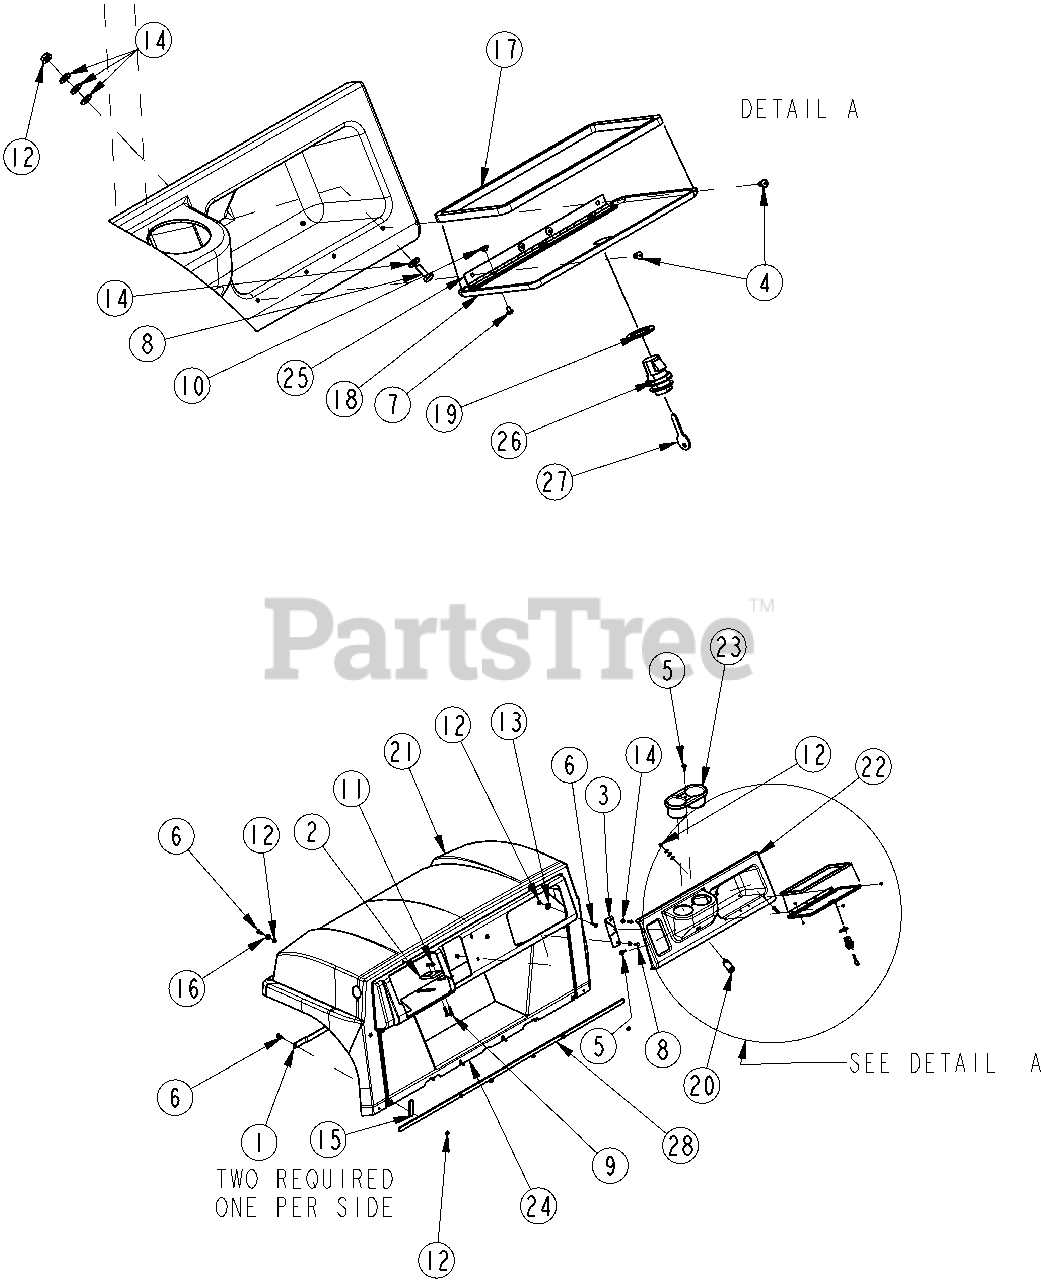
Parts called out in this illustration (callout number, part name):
1	BACKING PLATE FOR TRUCK BODY
2	BODY MOUNT SPACER .375 THICK As Required
2	BODY MOUNT SPACER .25 THICK As Required
3	DASH MOUNT PLATE
4	RIVET POP 3/16 .126-.250
5	RIVET, 1/4 REMOVEABLE
6	TPHMS Y 1/4-20X1 YELLOW DIE
7	PHMS #8-32 X 1/4, SS BLACK
8	HHCS 1/4-20X3/4 GR5
9	HHCS 5/16-18X1 1/4 GR5
10	NUT, BINDER 8-32 X 1/8
11	NUT HEX FLG TOP LK 5/16-18 YLW
12	NUT HEX FLNG T-LOCK 1/4-20 PLT
13	WASHER FLAT 3/8 USS PLT
14	WASHER FLAT 1/4 HARD ASTMF436
15	TRIM, 1/8 RUBBER EDGE (PER FT)
16	RUBBER GROMMET .75DX.31IDX.37T
17	SEAL, GLOVE BOX DOOR
18	DOOR, TRUCK GLOVE BOX
19	WASHER, 1 1/2 X 1 X .08 THICK
20	POWER PLUG OUTLET 12V
21	SERV - ST 4X2 BODY-RED W/DECAL
21	SERV - ST 4X2 BODY-CAMO/DECALS
21	SERV - ST 4X4 BODY-RED W/DECAL
21	SERV - ST 4X4 BODY-CAMO/DECALS
22	10 SERIES DASH W/DECALS
23	CUP HOLDER INSERT
24	4210ST FOOTWELL W/ DECALS
24	4410ST FOOTWELL W/ DECALS
25	HINGE, 1.25 X 10 CONTINOUS
26	LATCH, LOCKABLE TWIST
26	RPBY 840-306C & 817-661C
27	KEY GLOVE BOX DOOR- TWIST LOCK
27	KEY, GLOVE BOX DOOR- PUSH LOCK
28	FOAM RUBBER 3/16X3/4 THK W/PSA 52.5" Lg.
